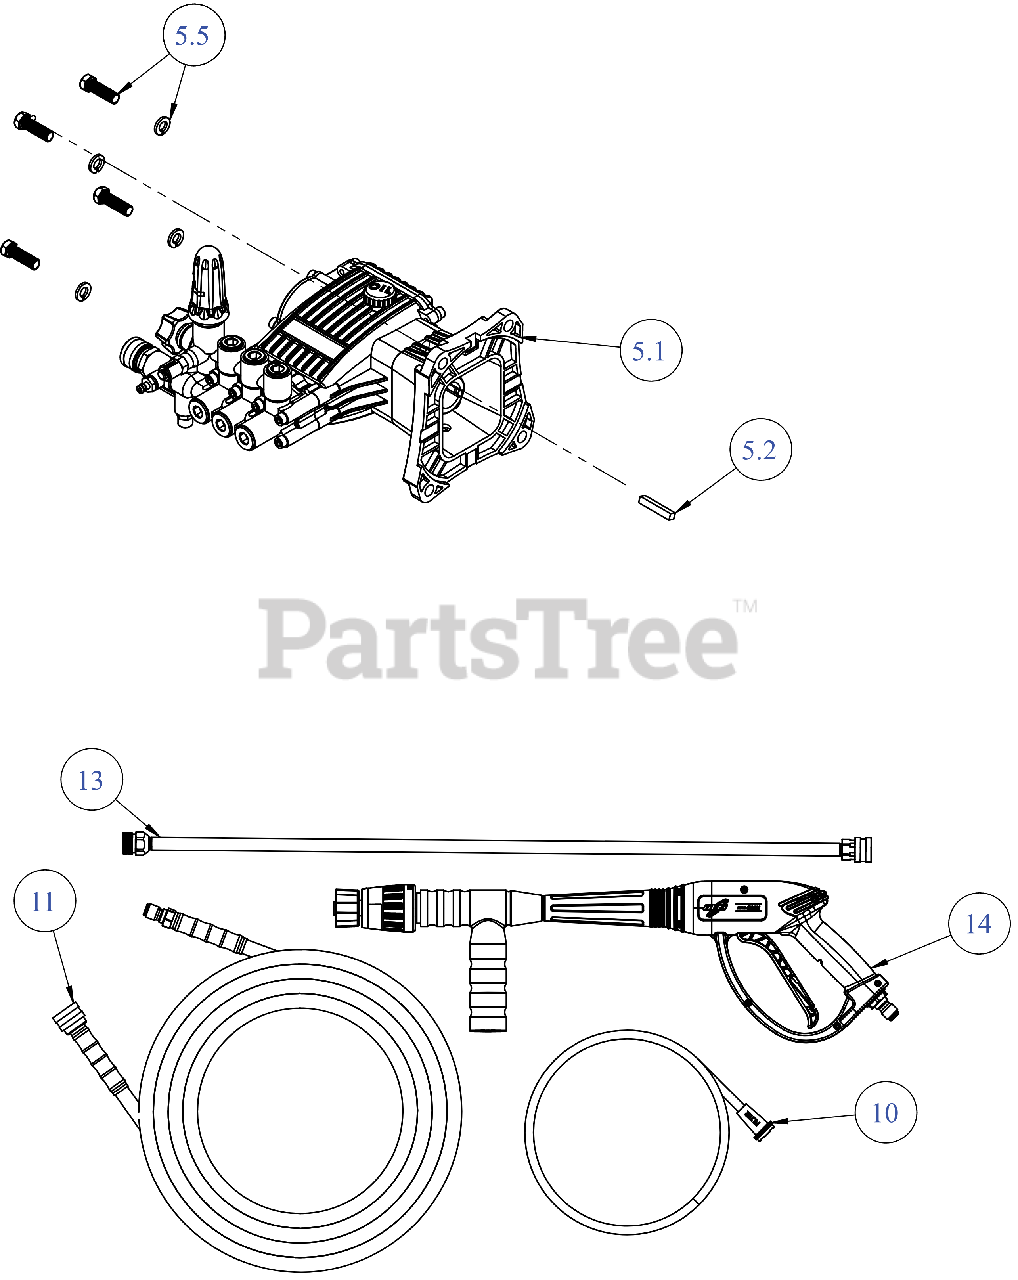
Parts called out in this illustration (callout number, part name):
5.1	PUMP ASSEMBLY
5.2	KEY: SHAFT 1/4" x 1/4" x 1.5"
5.5	KIT: PUMP MOUNITING HARDWARE
10	HOSE-SOAP W/FILTER
11	HOSE-SPRAY GUN 50'
13	WAND-SPRAY GUN 31"
14	GUN-SPRAY DIAL-N-WASH
